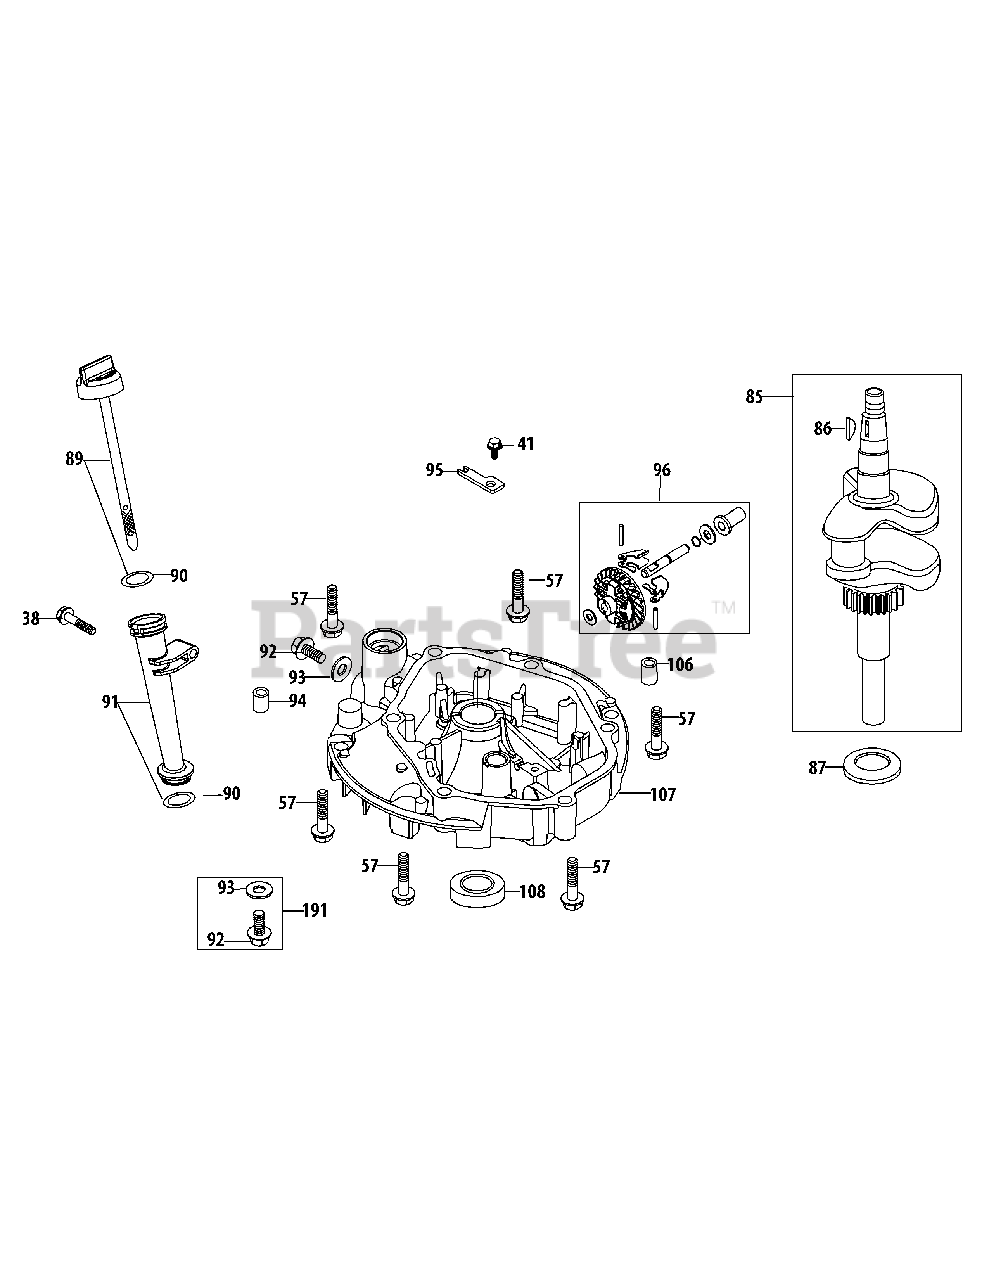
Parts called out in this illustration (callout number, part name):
38	Bolt M6X35
41	Bolt M6X14 Multi-Purpose
57	Bolt M8X50
85	Crankshaft Assembly
86	Woodruff Key
87	Crankshaft Thrust Washer
89	Dipstick Assembly
90	Dipstick / Oil Fill Tube O-Ring
91	Oil Filler Tube Assemlby
92	Oil Drain Plug
93	Oil Drain Plug Washer
94	Crankcase Cover Dowel Pin 9×14
95	Governor Gear Mounting Plate
96	Governor Gear/Shaft Assembly
106	Crankcase Cover Dowel Pin 7×14
107	Crankcase Cover
108	Lower Crankshaft Seal
191	Oil Drain Plug & Washer Assy
